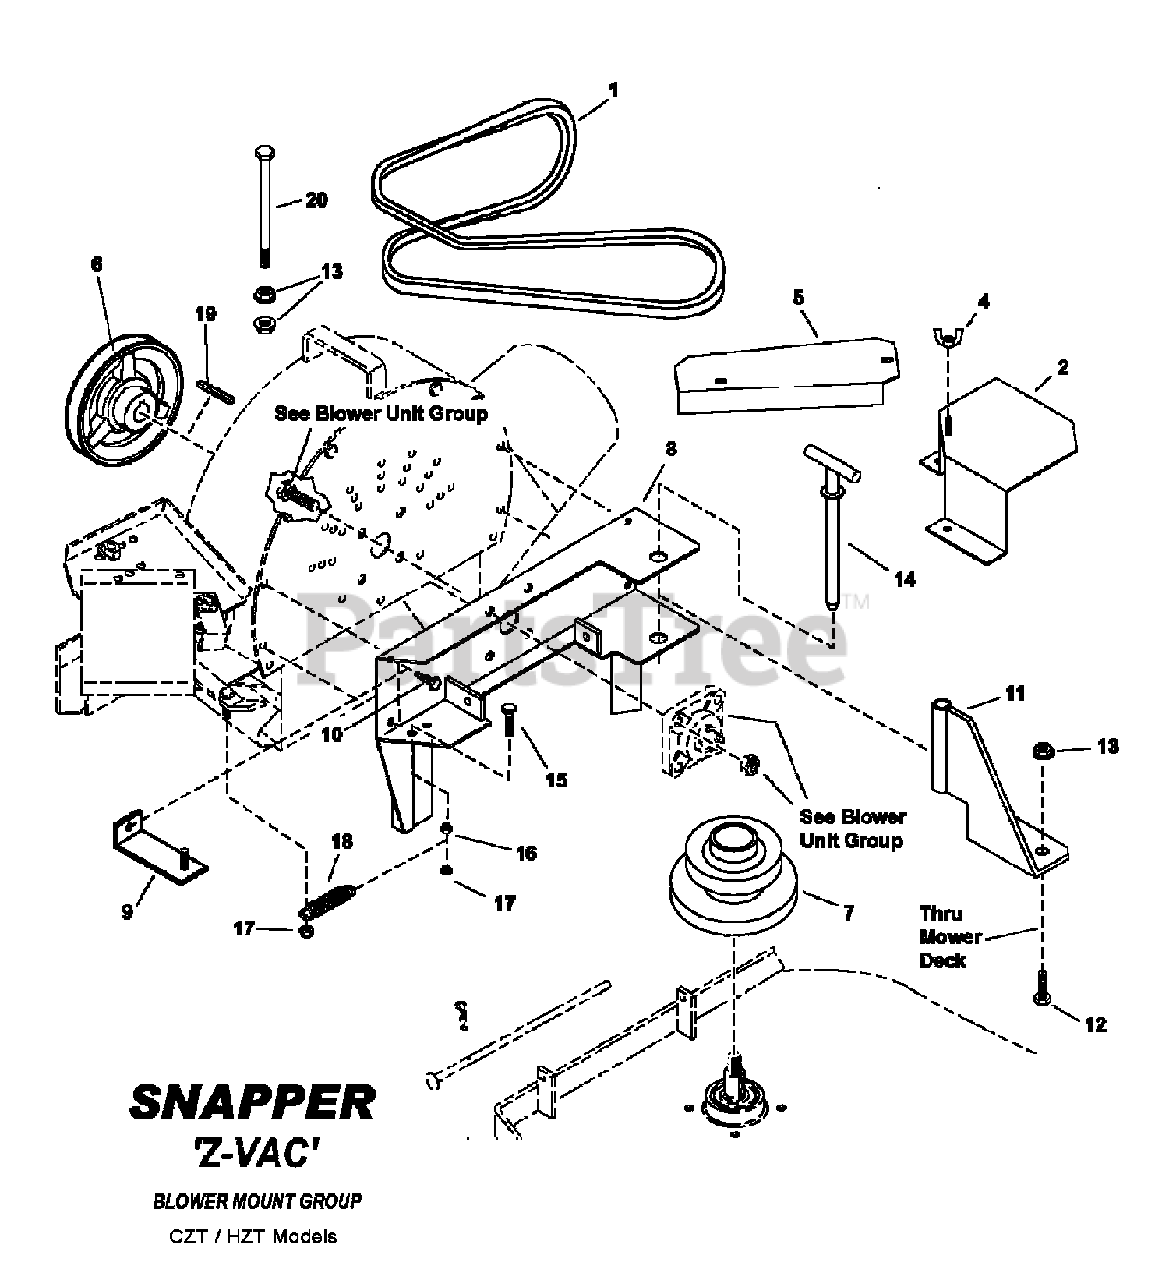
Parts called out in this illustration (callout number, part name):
1	BELT, A Section, 91.125" effective length
2	WELDMENT, Belt Cover, Deck
4	WING LOCKNUT 5/16-18
5	BELT GUARD
6	PULLEY, Blower Input
7	PULLEY, Spindle
8	WELDMENT, Blower Mount
9	WELDMENT, Guard Support Bracket
10	SCREW, 5/16-18 x 3/4" Hex Washer Self-Tap
11	WELDMENT, Deck Mount Bracket
12	SCREW, 3/8-16 x 1" Hex Head Cap, GR5
13	NUT, 3/8-16 Hex Flange Lock
14	WELDMENT, T-Handle Pin
15	SCREW, 5/16-18 x 1-1/4" Hex Head Cap, GR5
16	NUT, 5/16-18 Hex Flange Lock
17	NUT, 5/16-18 Hex Large Flange Center Lock
18	SPRING, Idler, Fast Vac
19	KEY, 1/4 Square x 1.44
20	SCREW, 3/8-16 x 6" Hex Head Cap, GR5
